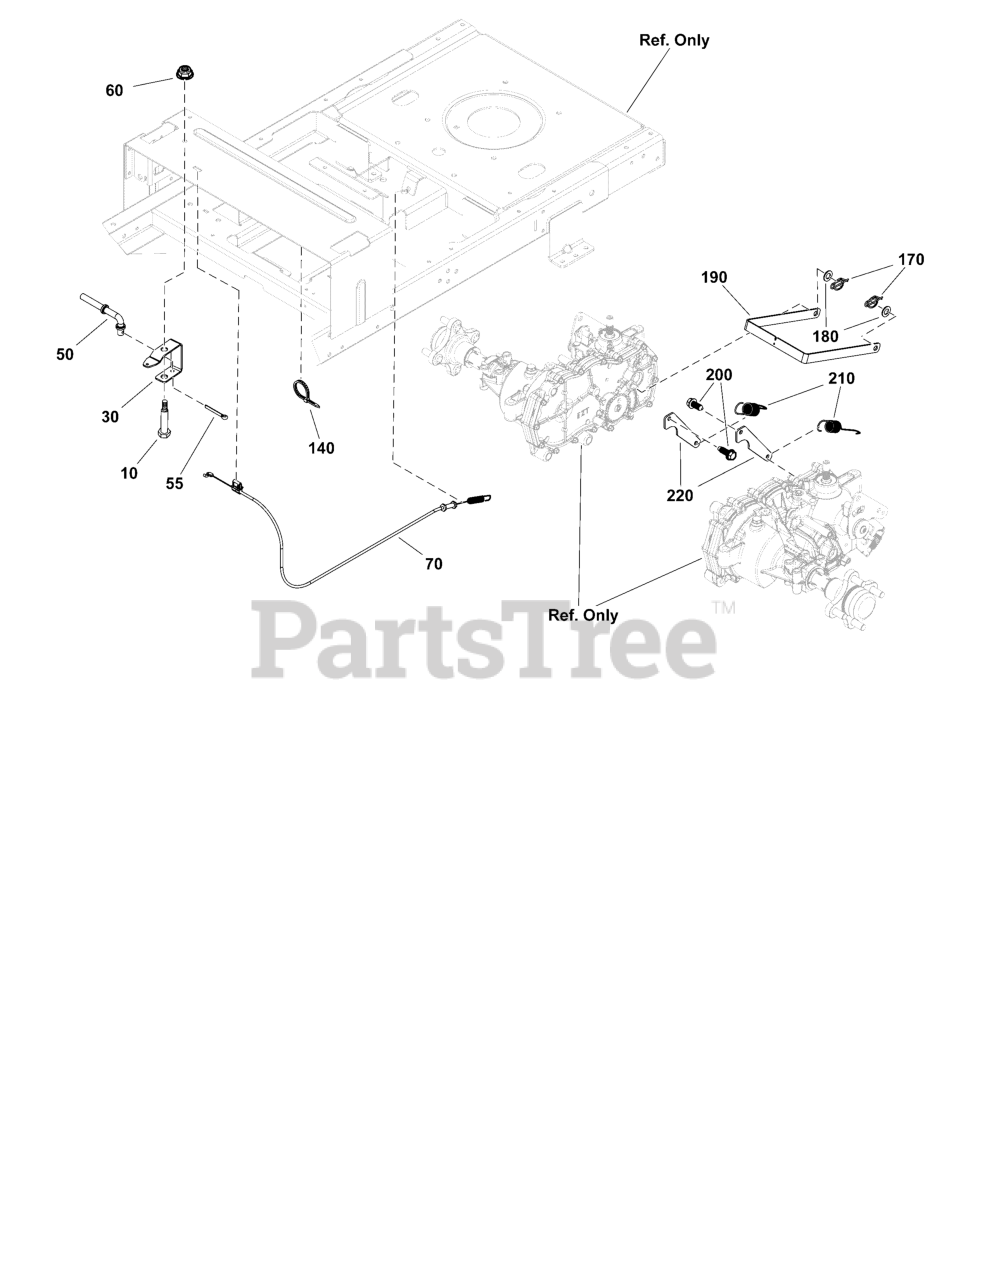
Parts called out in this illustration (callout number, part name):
10	SHOULDER BOLT, 3/8-16 x 3.41" .750 Thread Yellow
30	BELLCRANK, PARKING BRAKE
50	ROD, PARKING BRAKE
55	PIN, 3/32 X 0.750, COT, ZINC/CLEAR
60	NUT, 3/8 - 16 HEX NYLOCK FLANGE
70	CABLE, PARKING BRAKE
140	TIE, SELF-LOCKING, 12"
170	COTTER PIN, 1/2" Self-Locking
180	WSHR,0.390IDX0.720ODX0.054THK,FLAT,ZC/CL
190	ARM, PARKING BRAKE (EZT)(BLACK)
200	SCREW, TAPTITE, M6 X 1.0-12 LG
210	SPRING, EXTENSION
220	BRKT, BRAKE SPRING (EZT)
